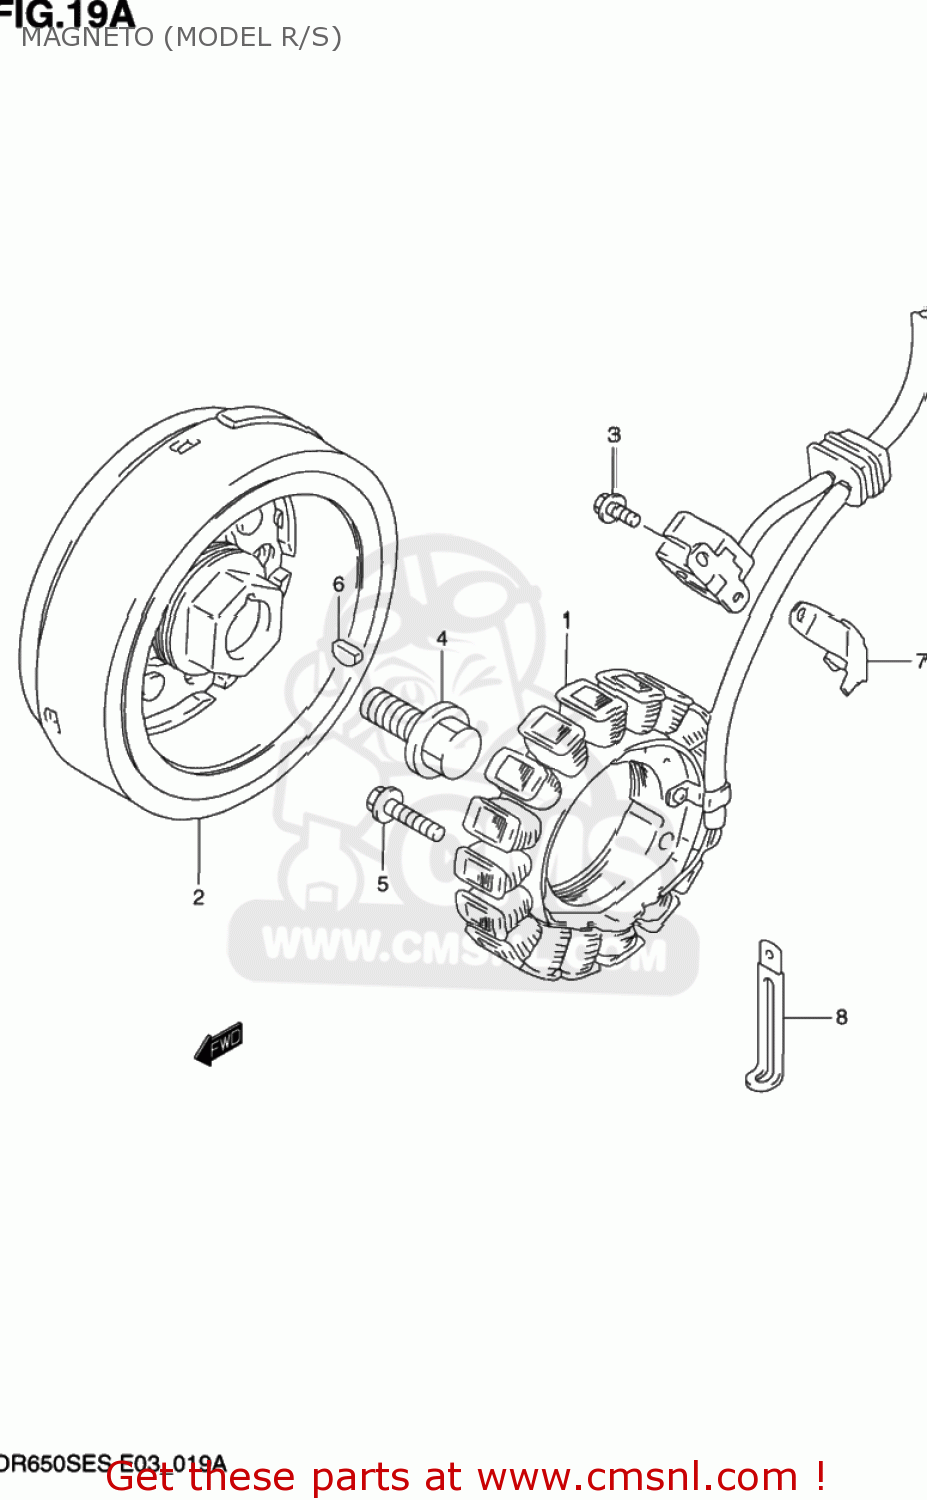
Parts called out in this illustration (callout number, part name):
1	STARTER ASSY
2	ROTOR
3	BOLT
4	BOLT(14X43)
5	BOLT
6	KEY
7	CLAMP,MAGNETO LEAD WIRE
8	CLAMP
